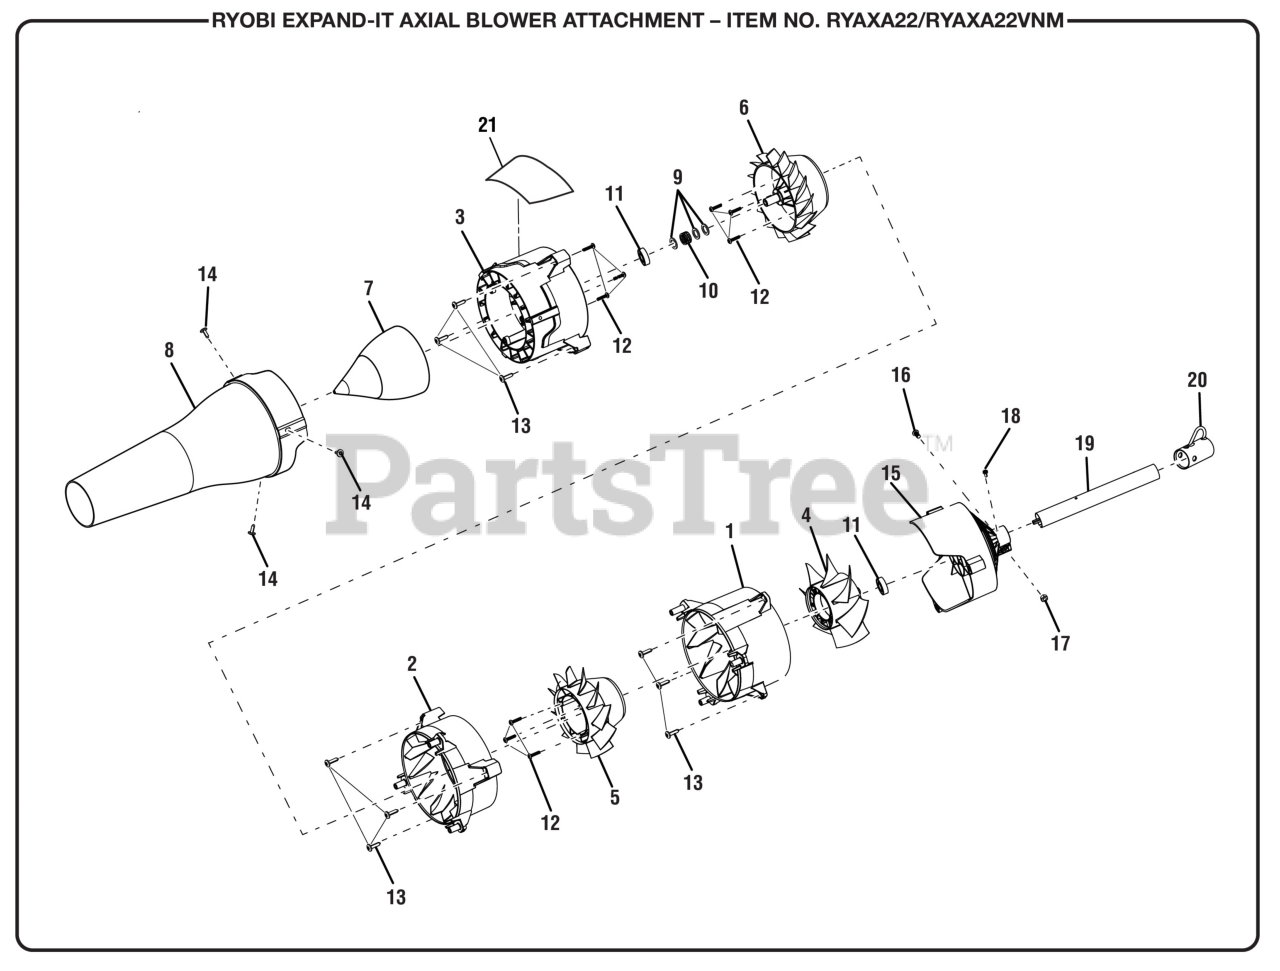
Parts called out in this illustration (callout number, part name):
1	Axial Stator (Stage One)
2	Axial Stator (Stage Two)
3	Axial Stator (Stage Three, Inc. Key No. 21)
4	Axial Fan (Stage One)
5	Axial Fan (Stage Two)
6	Axial Fan (Stage Three)
7	Reducer Cone
8	Reducer Nozzle
9	Washer (OD18 x ID12.15 x 1.5t)
10	Wavy Spring (ID6.51 x HGT9.52)
11	Ball Bearing (6001-zz)
12	Screw (M4 x 1.41 mm x 18 mm, T20 Torx Pan Hd. T.F)
13	Screw (10-14 x 19 mm, T25 Torx Truss Pan Hd. T.F.)
14	Vacuum Tube Screw (10-14 x 1/2 in., T25 Torx Truss Hd. T.F.)
16	Screw (M6 x 12 mm, T27 Torx Pan Hd.)
17	Hex Nut (M6.3 x 1)
18	Screw (M4 x 8 mm, T25 Torx Pan Hd. T.F.)
19	Boom Assembly
20	Hanger Cap
21	Safety Icon Label
